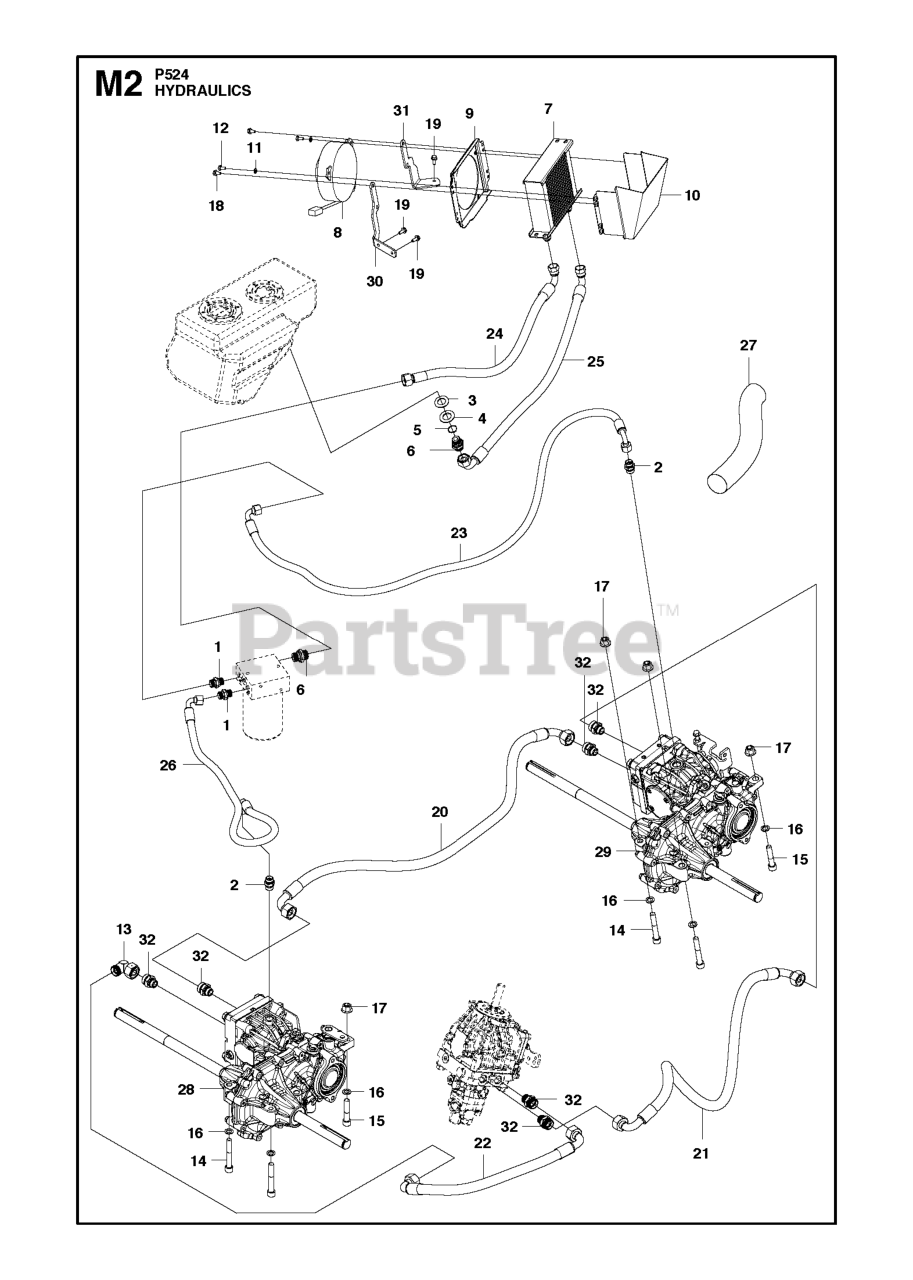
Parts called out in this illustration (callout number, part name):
11	WASHER - M6
18	SCREW EHHFM
19	Screw
